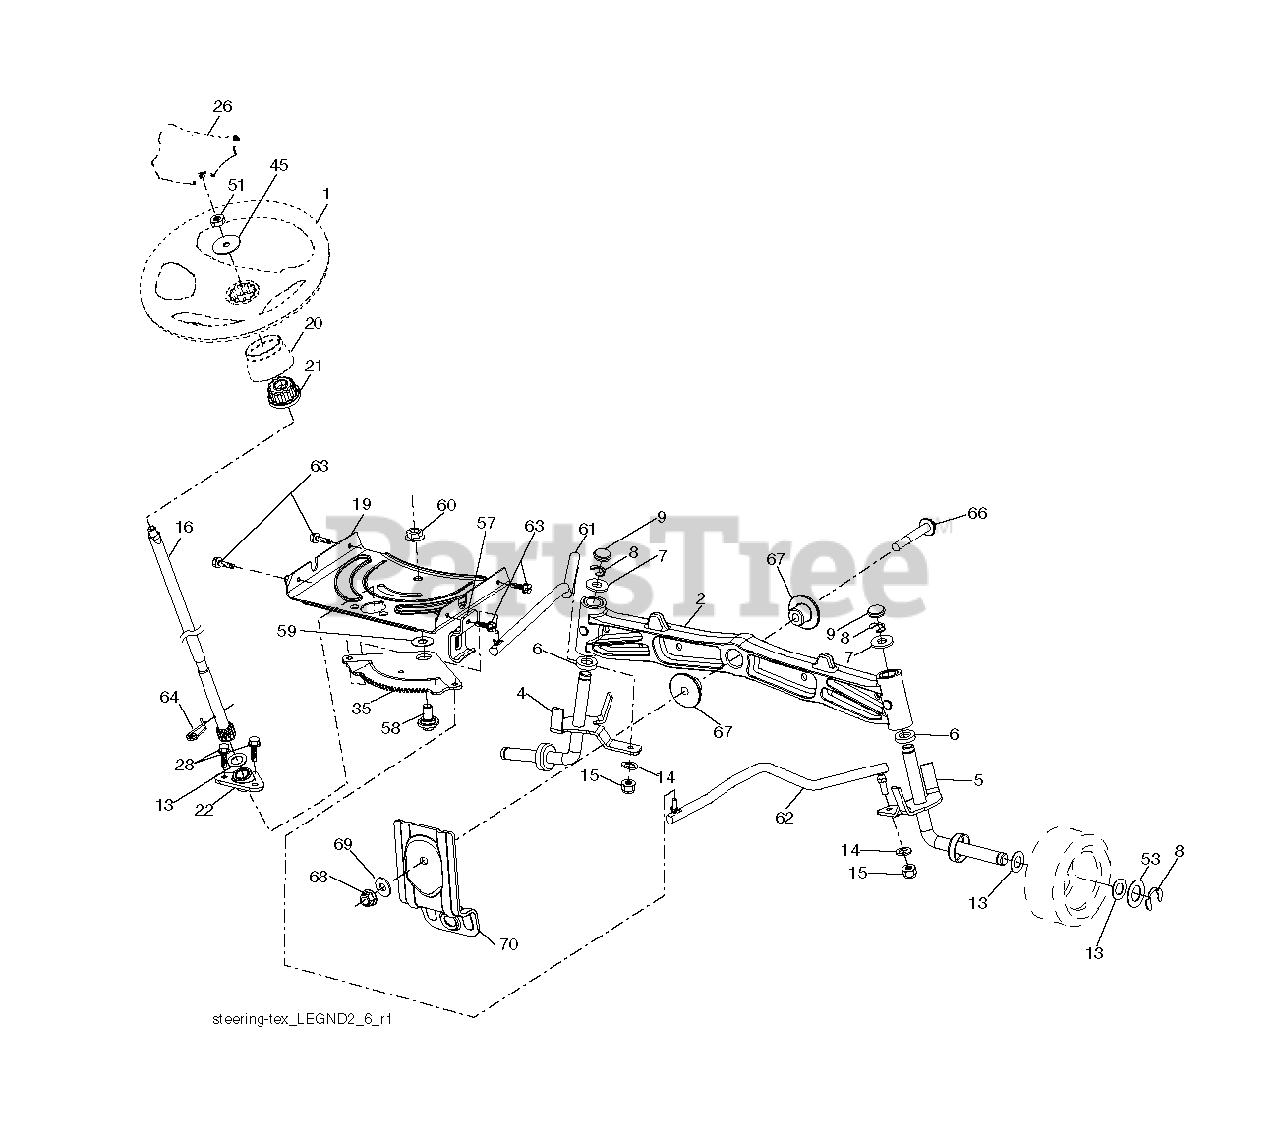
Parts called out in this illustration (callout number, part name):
1	WHEEL.STEERING.MLT.BR.YEL/OVRM
2	AXLE.CAST.IRON
4	SPINDLE.WELDED.LH.16"TEX
5	SPINDLE.WELDED.RH.16"TEX
8	RING CLIP
9	CAP.SPINDLE.BLACK
14	WASHER, LOCK 3/8
15	NUT CROWNLOCK 3/8-24
16	SHAFT, STEERING
19	PLATE.STEER.DDL.NLT/NG
20	BOOT, STEERING
21	ADAPTER, WHEEL STNG..
22	STEERING.SUPT.LOWER.
26	CAP.WHL.STRNG.MULTI.BRND.YEL
28	SCREW, 3/8-16X3/4
35	GEAR.SECTOR.PLATE.DDL.
45	WASHER 9/16"ID, 2 3/8""OD
51	NUT.HEX.1/2-20
53	WASHER.HARDENED
57	BRKT.UPSTOP.GT/LT.TEX
58	BOLT.SHOULDER.SECTOR.P
59	WASHER.THURST.SECTOR.S
60	NUT FLANGE LOCK 5/8-11
61	DRAGLINK.LH.BALLSTUD.D
62	DRAGLINK.RH.BALLSTUD.D
63	SCREW
64	RETAINER.CLIP.SPRING.S
66	BOLT HEX FGHD 7/16-14 X 3 SERR
67	BUSHING.PM.FRONT AXLE
68	NUT.LOCK.FLANGE.7/16
69	WASHER.1.5X.505X.118
70	BRKT.DECK.SUSPENSION.F
